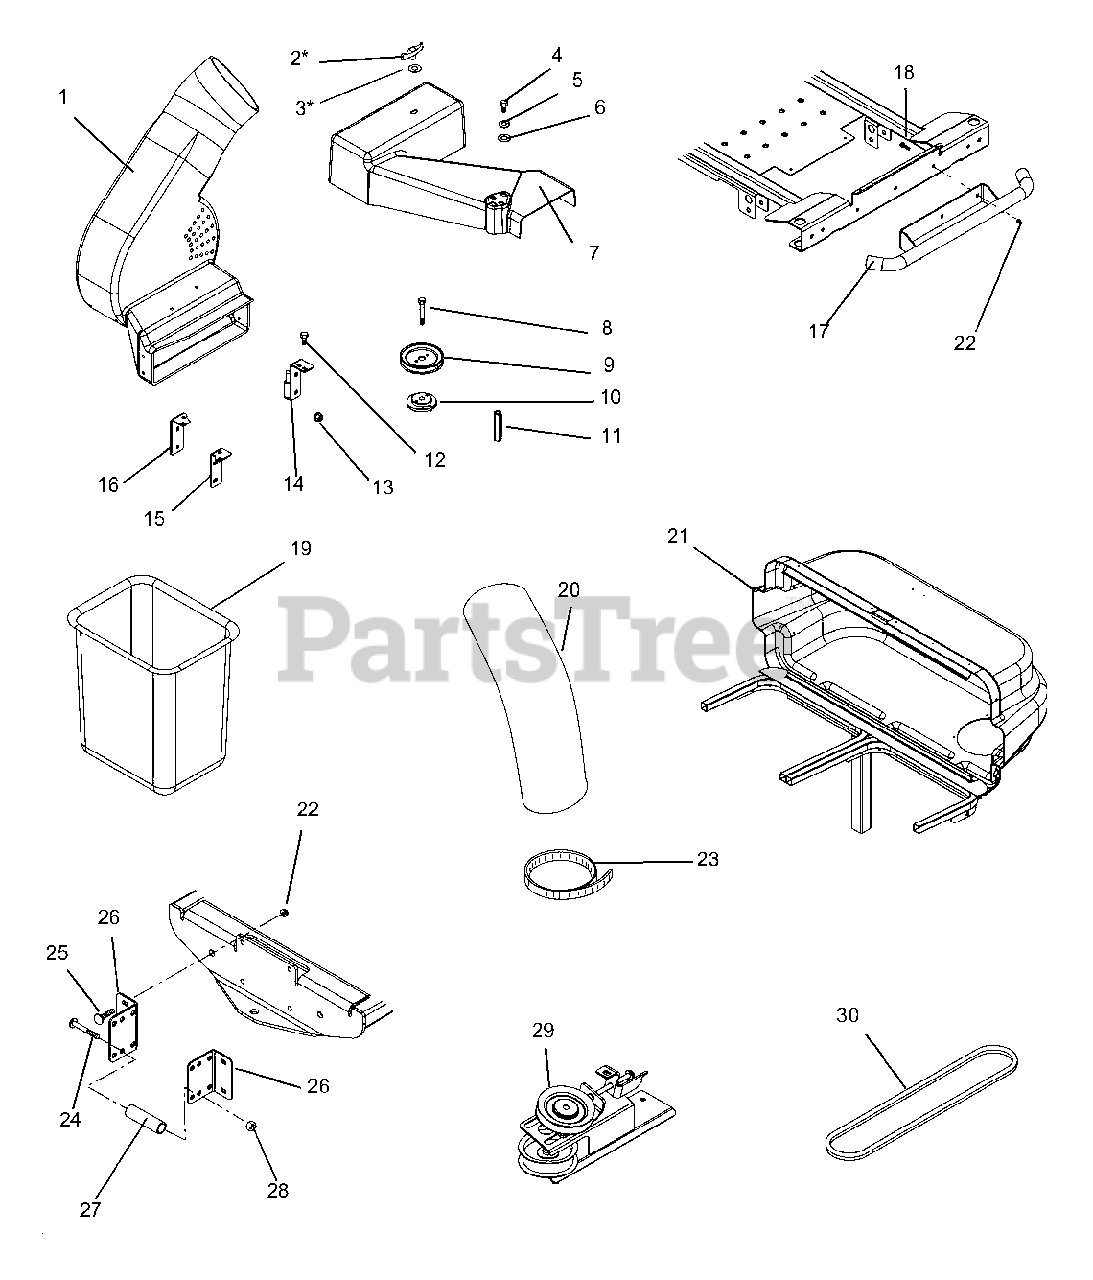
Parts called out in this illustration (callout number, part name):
1	Blower Assembly
2	Wing Knob
3	3/8" x 1-1/2" Washer
4	3/8" x 3/4' Hex Bolt
5	3/8" Lock Washer
6	7/16" x 1" Flat Washer
7	Belt Cover
8	3/8" x 1-3/4" Hex Bolt
9	3-Inch Sheave (40-Inch Mower Deck)
9	4-Inch Sheave (34-Inch Mower Deck)
10	Sheave Adapter
12	1/4" x 3/4" Hex Bolt
13	1/4" Top Lock Flange Nut
14	Rear Mount Weldment Bracket
15	Front Bracket
16	Front Mount Weldment Bracket
17	Front Bumper
18	3/8" x 1" Hex Bolt
19	Grass Bagger Basket
20	Hose
21	Cover Assembly
22	3/8" Flange Nyloc Nut
23	Hose Clamp
24	1/2" x 3" Hex Bolt
25	3/8" x 1-1/4" Round Head Square Neck Bolt
26	Bagger Mount Bracket
27	Pivot Spacer
28	1/2" Top Lock Flange Nut
29	Idler Assembly
30	V-Belt
